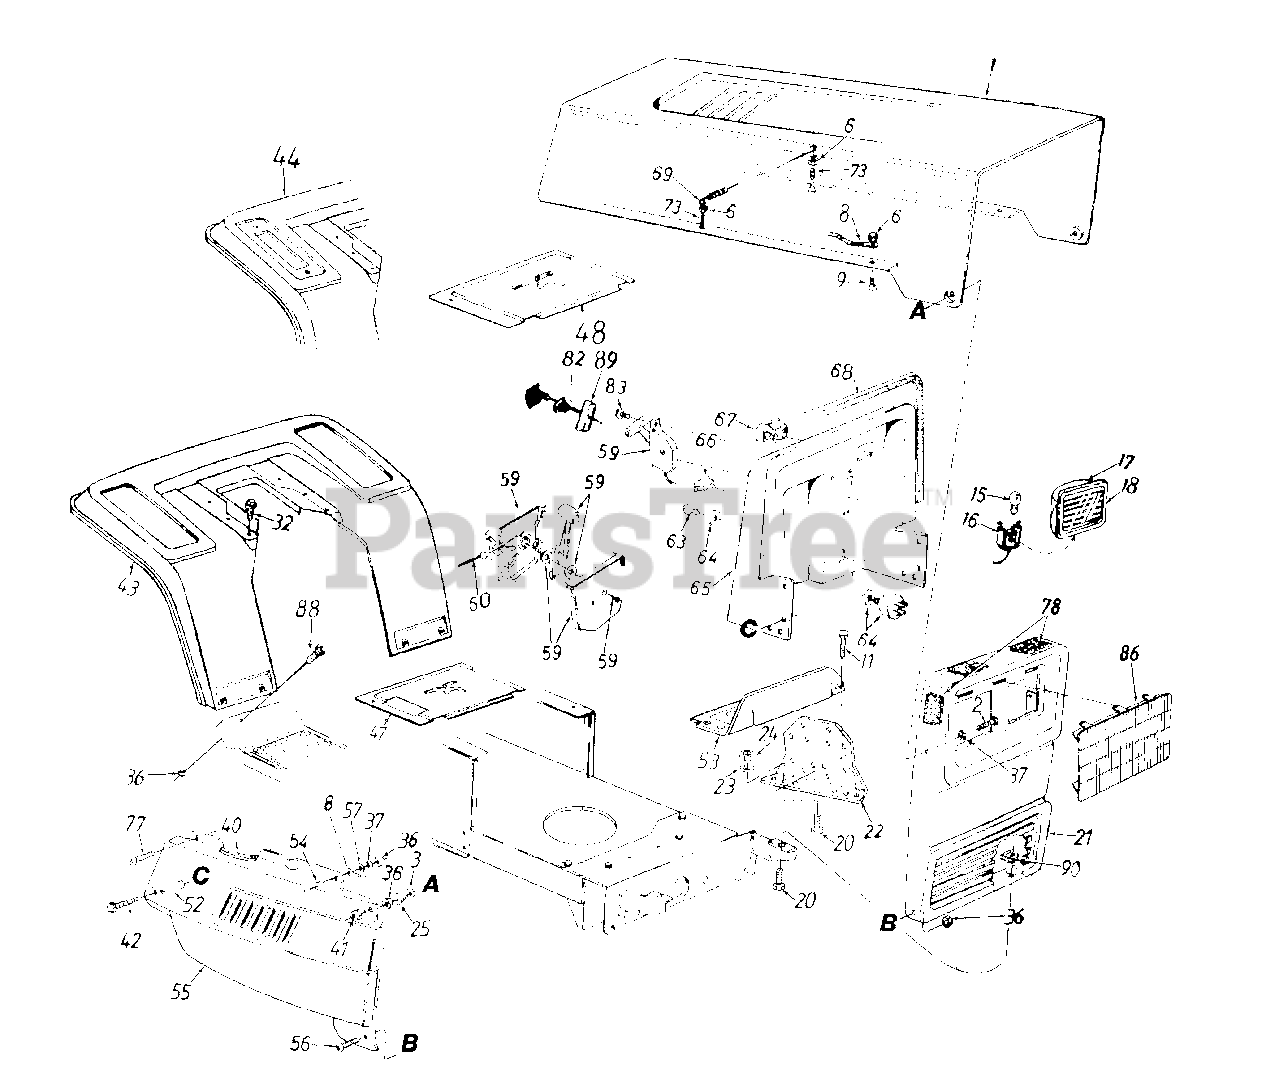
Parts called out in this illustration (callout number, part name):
3	Washer .39" I.D. x .62"
6	Hex Sems Nut #10-24 Thd.
8	Hood Stop
9	Truss Hd. Scr. #10-24 x 1/2"
11	Hex Wash. Hd. B-Tap Scr.5/16-18 x .5"
15	Bulb
16	Twist Lock Bulb Socket
17	Headlight Housing
18	Lens
20	Hex Bolt 5/16-18 x .75" Lg.
24	Hex Nut 5/16-18 Thd.
25	Shld. Spacer
36	Hex Sems Nut 1/4-20 Thd.
40	Trim Strip 12"
41	Acorn Nut 1/4-20 Thd.
42	Hex TT-Tap Scr. 1/4-20 x 1.75"
52	Spacer 1.32" Lg.
57	Fl-Wash. .281" I.D. x .73" O.D.
59	Throttle Control Box Ass'y.
60	Throttle Control Wire 18.5" Lg.
63	Ignition Key
64	Ignition Switch
67	Ammeter
68	Trim Strip 31"
69	Hood Spring
73	Hex Scr. #10-24 x 1.0" Lg.
77	Hex Wash. Hd. Tap Scr.1/4 x .75" Lg.
78	Foam Strip 3/8 x 1-1/8" x 1-1/2 Lg.
82	Choke Control 29" Lg.
83	Truss Mach. AB-Tap Scr.#10 x .5" Lg.
86	Headlight Bezel
88	Truss Mach. Scr. 1/4-20 x .5" Lg.
89	Retainer Clip
90	U-Nut 5/16-18 Thd.
